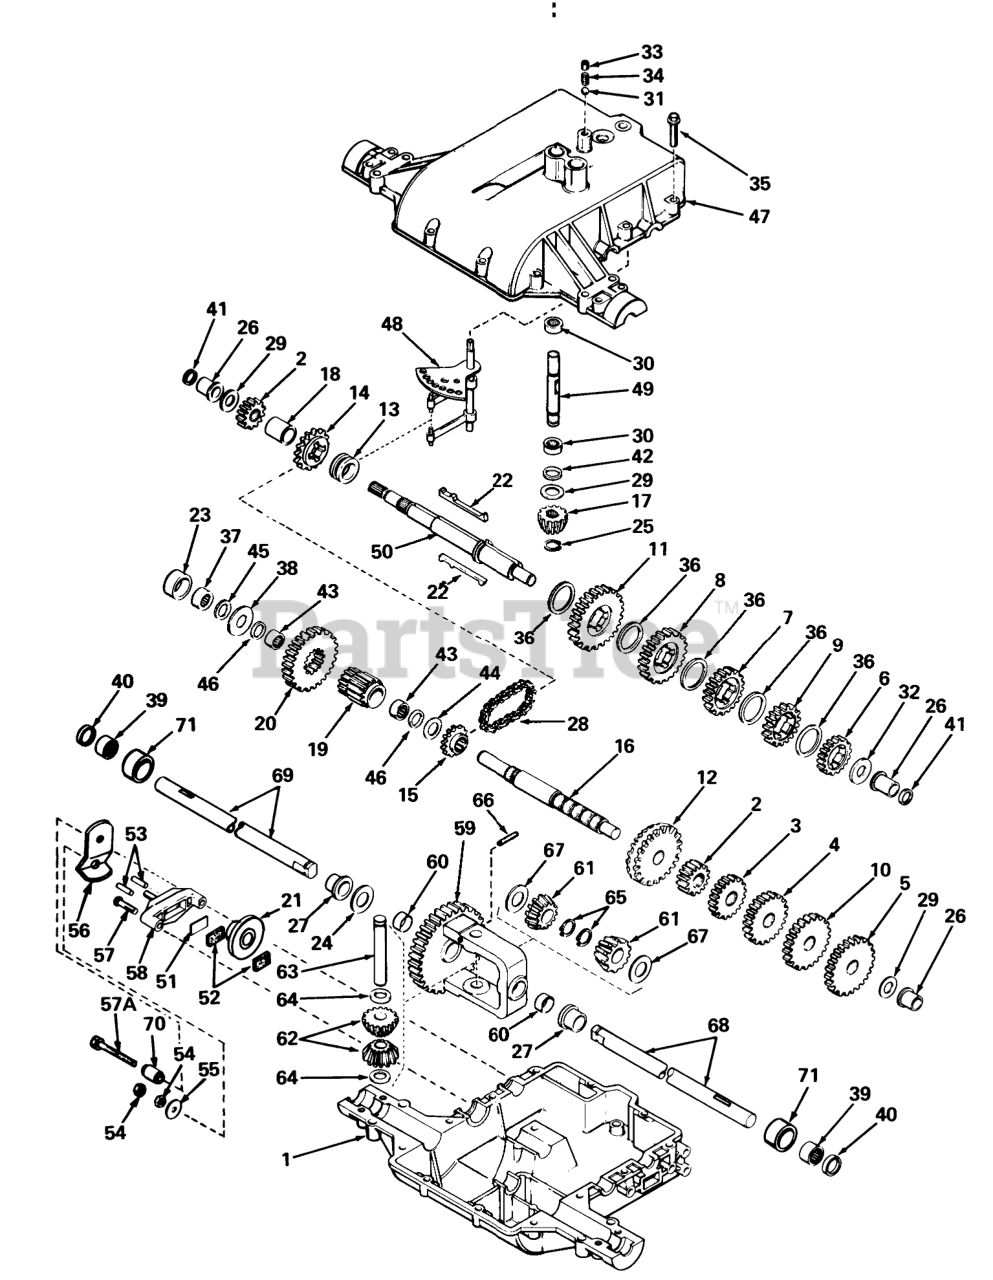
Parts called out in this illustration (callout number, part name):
1	Case, Transaxle
2	Gear-Spur 15 Teeth
3	Gear, Spur (20 teeth)
4	Gear, Spur (25 teeth)
5	Gear, Spur (30 teeth)
6	Gear-Spur 20 teeth
7	Gear, Spur (25 teeth)
8	Gear, Spur (30 teeth)
9	ASpur Gear (22 Teeth)
10	Gear, Spur (28 teeth)
11	Gear-Spur, 35 Teeth
12	Gear, Bevel (42 teeth)
13	Collar-Shift
14	Sprocket-18 Teeth
15	Sprocket-9 Teeth
16	Shaft-Counter
17	Bevel Pinion-Input
18	Spacer
19	Pinion-Output
20	Gear-Output
23	Spacer
24	Washer
25	Ring-Retainer
26	Bushing, Flanged
27	Bronze Bearing
28	Chain-Roller #41
29	Washer
30	Bearing-Needle
31	Ball-Steel
32	Washer
33	Screw-Set
34	Spring
35	Ring Set (.020 O S)
36	Washer
37	Bearing-Needle
38	Washer-Flat
39	Bearing-Cartridge
40	Seal Oil
41	Ring-Square Cut
42	O Ring
43	Bearing-Needle
44	Washer-Flat
45	Ring-Square Cut
46	Ring-Square Cut
47	Cover, Transaxle
48	Rod & Fork Assembly
49	Shaft, Input
50	Shaft, Brake
51	Brake Pad Plate
52	Brake Pad
53	Dowel Pin
54	Locknut
55	Washer
56	Lever-Brake
57	Ring Set (.020 O S)
57A	Screw-Hex. Flange
58	Holder-Brake Pad
59	Gear Assy., Differential (Incl.2 of No. 60)
60	Bushing
61	Bevel Gear
62	Gear Pinion
63	Drive Pin
64	Thrust Washer
65	Snap Ring
66	Pin-Roll
67	Washer
68	Axle (14-7/8" long)
69	Axle (13" Long)
70	Spacer
71	Sleeve
